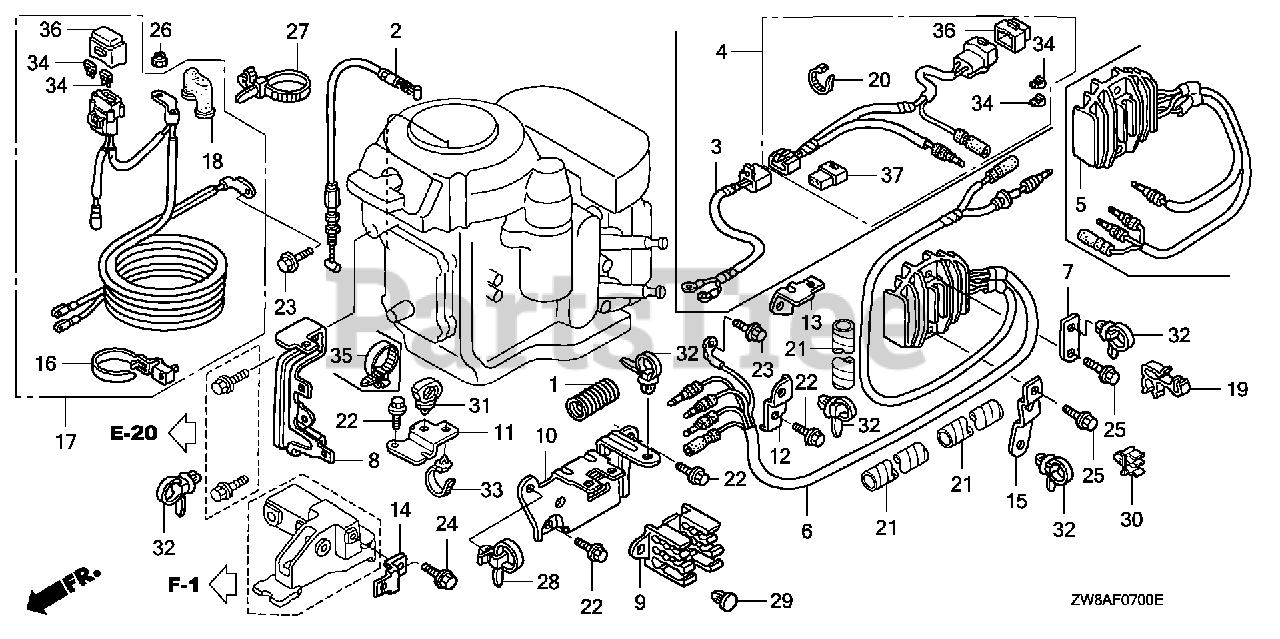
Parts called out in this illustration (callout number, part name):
1	TUBE, CORRUGATE (15MM)
2	CABLE, NEUTRAL STARTING
6	RECTIFIER ASSY., REGULATOR
7	BRACKET, CLIP F
8	BRACKET, CONNECTOR A
9	BRACKET, CONNECTOR (B)
10	BRACKET, CONNECTOR C
11	BRACKET, STARTER CABLE
12	BRACKET, CLIP B
13	BRACKET, FUSE CASE
15	BRACKET, E-CLIP
16	BAND, WIRE
17	CABLE ASSY., STARTER
18	COVER, MAGNETIC SWITCH TERMINAL
19	CLAMP, DISTRIBUTOR WIRE
21	TUBE, SPIRAL A
22	BOLT, FLANGE (6X14) (CT200)
23	BOLT, FLANGE (6X12)
25	BOLT, FLANGE (6X26) (CT200)
26	NUT, LOCK (6MM)
27	BAND, WIRE (95MM)
28	STRAP, CABLE (118MM) (BLACK)
29	CLIP, ANCHOR
30	CLIP, FUEL TUBE
32	CLIP, HARNESS BAND (151.5MM) (NATURAL)
33	BAND, WIRE HARNESS (123.5MM) (BLUE)
34	FUSE, BLADE (20A)
36	COVER ASSY., FUSE (20A)
